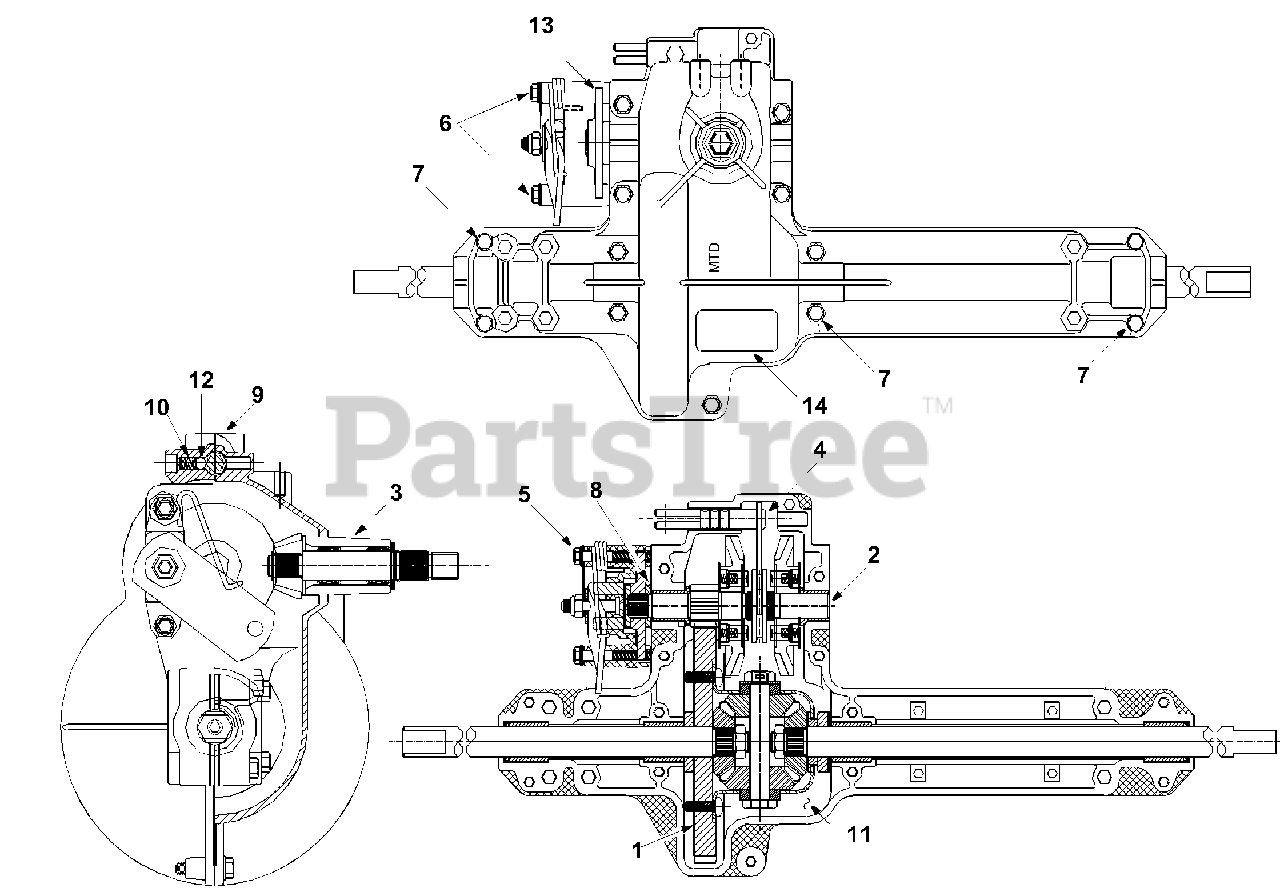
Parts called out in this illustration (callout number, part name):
1	Differential Assembly: Single Speed
2	Drive Shaft assembly: LH Brake
3	Upper Housing Assembly
4	Detent Shaft Assembly
5	Brake Yoke Assembly: LH
6	Hex Washer Hd. TT Screw 1/4-20 x 2.37 Gr.5
7	Hex Washer Hd. TT Screw 1/4-20 x 1.65
8	Brake Puck
9	Lower Housing
10	Spring Detent
11	Grease
14	Label
